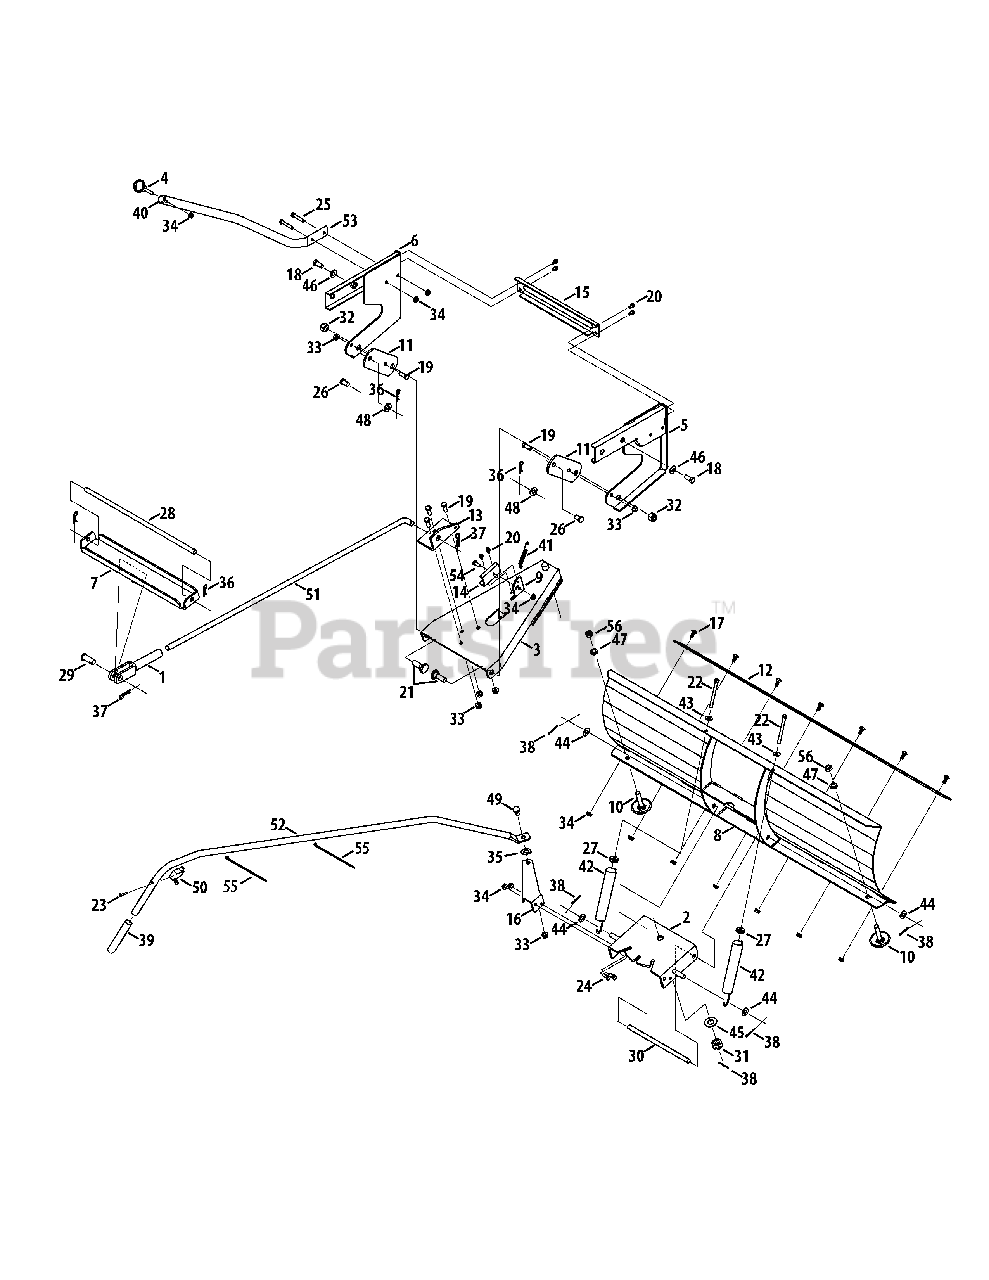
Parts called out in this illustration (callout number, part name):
1	Adjustment Clevis Assembly
2	Blade Pivot Assembly
3	Blade Frame Assembly
4	Eyebolt Assembly
5	RH Hitch Bracket Assembly
6	LH Hitch Bracket Assembly
7	Lift Bracket Assembly
8	Blade Assembly, 46"
9	Blade Lock Plate Assembly
11	Blade Link Bracket
12	Shave Plate, 46"
13	Front Lift Bracket
14	Pivot Bracket
15	Snowblade Support Bracket
16	Blade Adjustment Arm
17	Carriage Bolt, 5/16-18 x .750
18	Hex Screw, 7/16-14 x 1.00
19	Hex Screw, 3/8-16 x 1.00
20	Hex Washer Screw, 1/4-20 x 0.500
21	Shoulder Screw, 1/2-13 x .625 x .36
22	Hex Screw, 5/16-18 x 3.50
23	Machine Screw, #10-24 x 1.375
24	Hex Screw, 5/16-18 x .75
25	Hex Screw, 5/16-18 x 1.75
26	Clevis Pin, .50 x .78
27	Spring Insert
28	Rod, .50 x 18.61
29	Clevis Pin
30	Rod, .50 x 10.428
31	Slotted Nut, 3/4-16
32	Nut, 1/2-13, Hex Lock Nylon
33	Flange Lock Nut, 3/8-16
34	Flange Lock Nut, 5/16-18
35	Flat Teflon Washer, .570 x 1.12 x .062
36	Click Pin, .092 x 1.64
37	Cotter Pin, .125 x 1.75
38	Cotter Pin, 1/8 x 1.25
39	Foam Grip
41	Extension Spring, .38 x 3.25
42	Extension Spring, 1.25 x 6.7
43	Flat Washer, .349 x .879 x .063
44	Flat Washer, .530 x .930 x .050
45	Flat Washer, .760 x 1.50 x .120
46	Bell Washer, .45 x 1.00 x .062
47	Lock Washer, 1/2
48	Flat Washer, .531 x 1.062 x .134
49	Shoulder Bolt, .496 x .336 x 3/8-16
50	Blade Release Cable & Lever
52	Blade Adjustment Handle
53	Handle Support Tube
54	Shoulder Screw, 5/16-18 x .405 x .435
55	Cable Tie
56	Nut, 1/2-13, Jam
